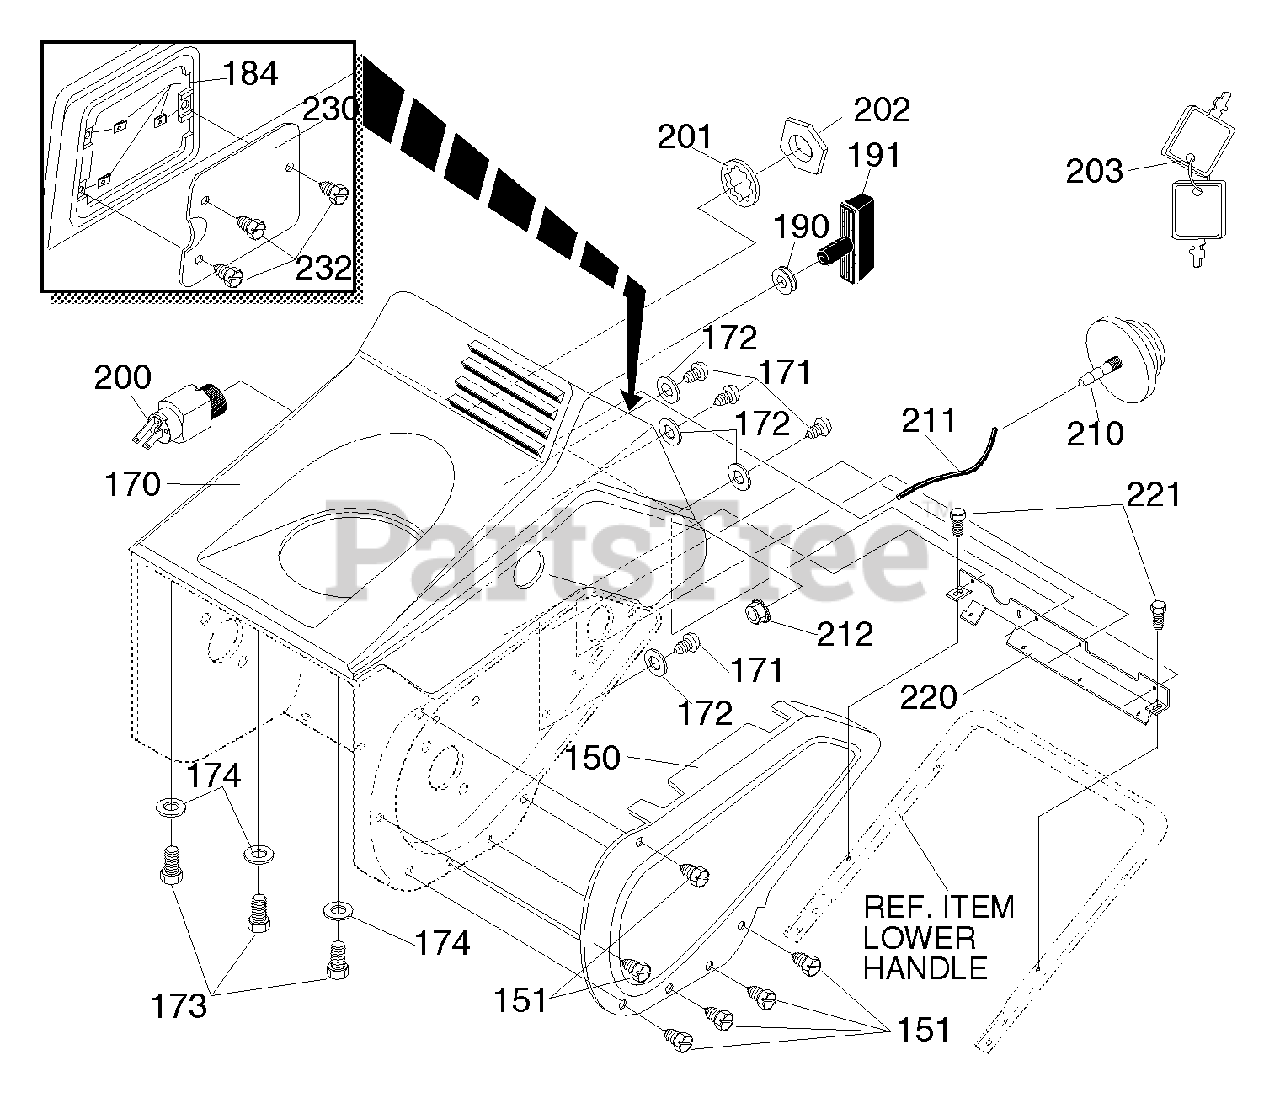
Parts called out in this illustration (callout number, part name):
150	BELT COVER
151	SCREW, 10-24 X .38
170	COVER, TOP
171	SCREW, #10-24 X .63 TAP
172	FLATWASHER .203 X .56 X .049
173	SCREW, #10-24 X .63
174	FLATWASHER .250 X .56 X .049
184	NUT, TINN "U" TYPE
190	GROMMET & WASHER
191	GRIP, MITTEN
200	SWITCH, IGNITION
201	WASHER, REGINTLK
202	NUT, 5/8-32 HXHD IGN. SWITCH
203	2 KEYS & RING ASSY
210	PRIMER, ENGINE
211	HOSE, PRIM
212	NUT, 1/4-20 HEXKEPS
220	BRACKET, SHROUD MTG
221	SCREW #10-24 X .63 TAP
232	SCREW #10-16 X .75
